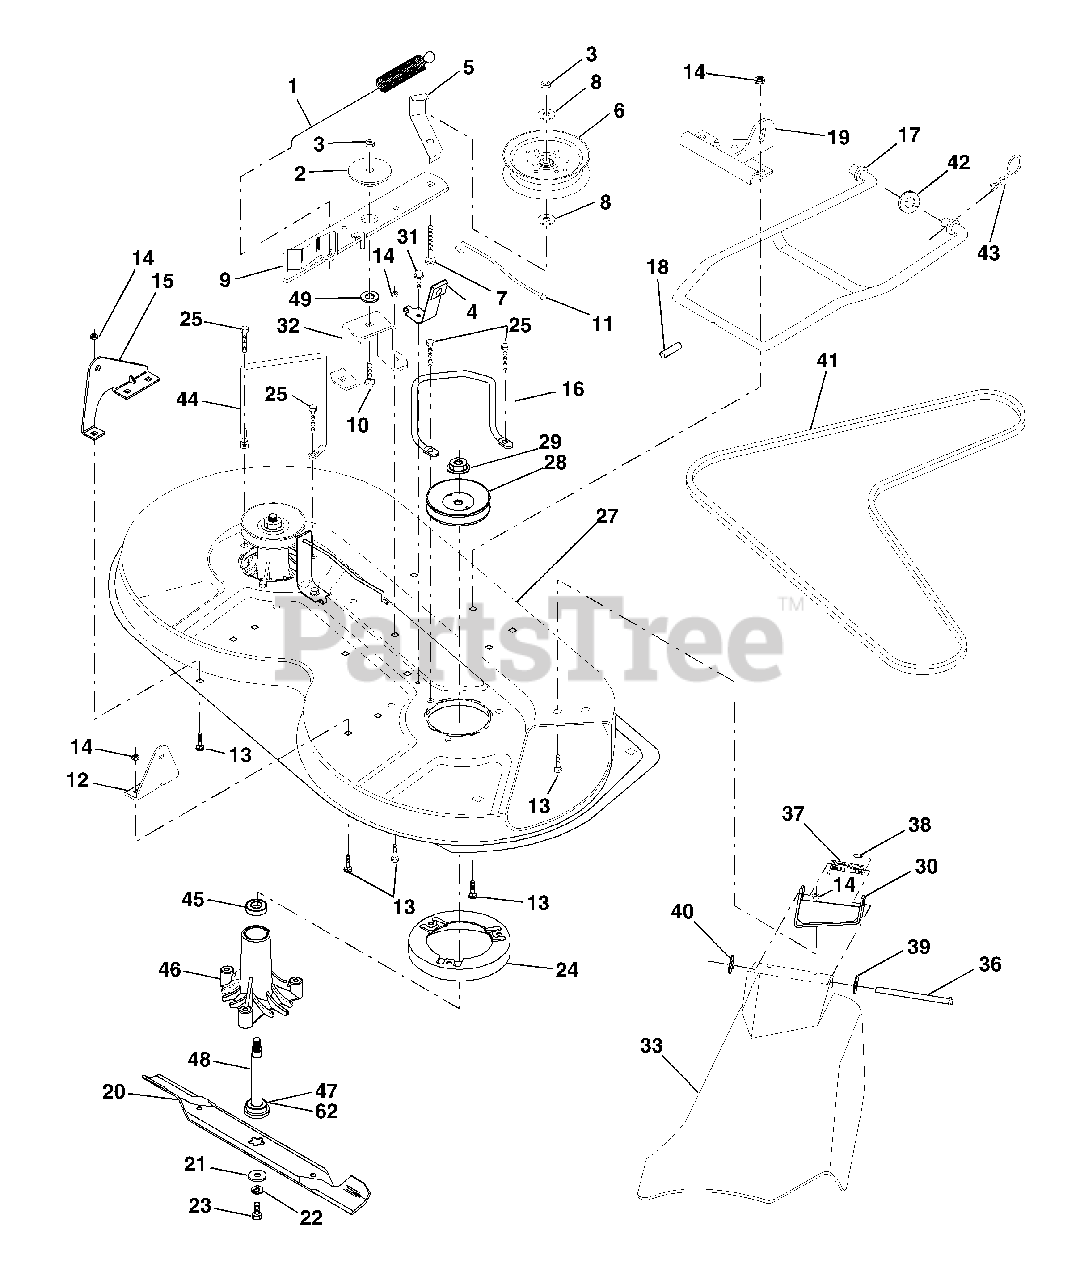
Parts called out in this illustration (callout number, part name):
1	Spring, Mower Clutch
2	Spacer, Retainer
3	Nut, Crownlock 3/8-16
4	Brake Asm.
5	Guide, Belt Idler
6	Pulley, Flat Idler
7	Bolt, Carr. 3/8-16 x 1-3/4 Gr. 5
8	Washer 13/21 x 7/8 x 10 Ga.
9	Arm Asm., Idler Mower
10	Bolt, Carriage 3/8-16 x 1-1/4
11	Rod, Brake
12	Bracket, Lift R. H. Rear
13	Bolt, Carriage 5/16-18 x 3/4
14	Nut, Crownlock 5/16-18
15	Bracket, Lift L. H. Rear
16	Keeper, R. H.
17	Link, Asm. Mower Stabilizer
18	Pin, Drive
19	Bracket, Asm. Front
20	Blade High Lift
21	Washer, Hardened
22	Washer, Lock 3/8
23	Bolt 3/8-24 x 1-1/4 Gr. 8
24	Stripper
25	Screw Thdrol Hex Hd
27	Deck Assembly
28	Pulley, Mandrel
29	Nut, Flange Lock 9/16
30	Bracket, Asm. Deflector
31	Screw, Hex Wsh. Thdrol. 5/16-18 x 1/2
32	Arm, Support Idler Mower
33	Deflector
36	Rod, Hinge
37	Spring, Torsion Deflector
38	Cap, Sleeve
39	Washer 11/32 x 5/8 x 16 Ga.
42	Washer 11/32 x 5/8 x 16 Ga.
43	Retainer, Spring
44	Keeper, L. H.
46	Housing Mandrel Vented
48	Shaft, Mandrel
49	Washer Hardened
62	Washer, Felt
